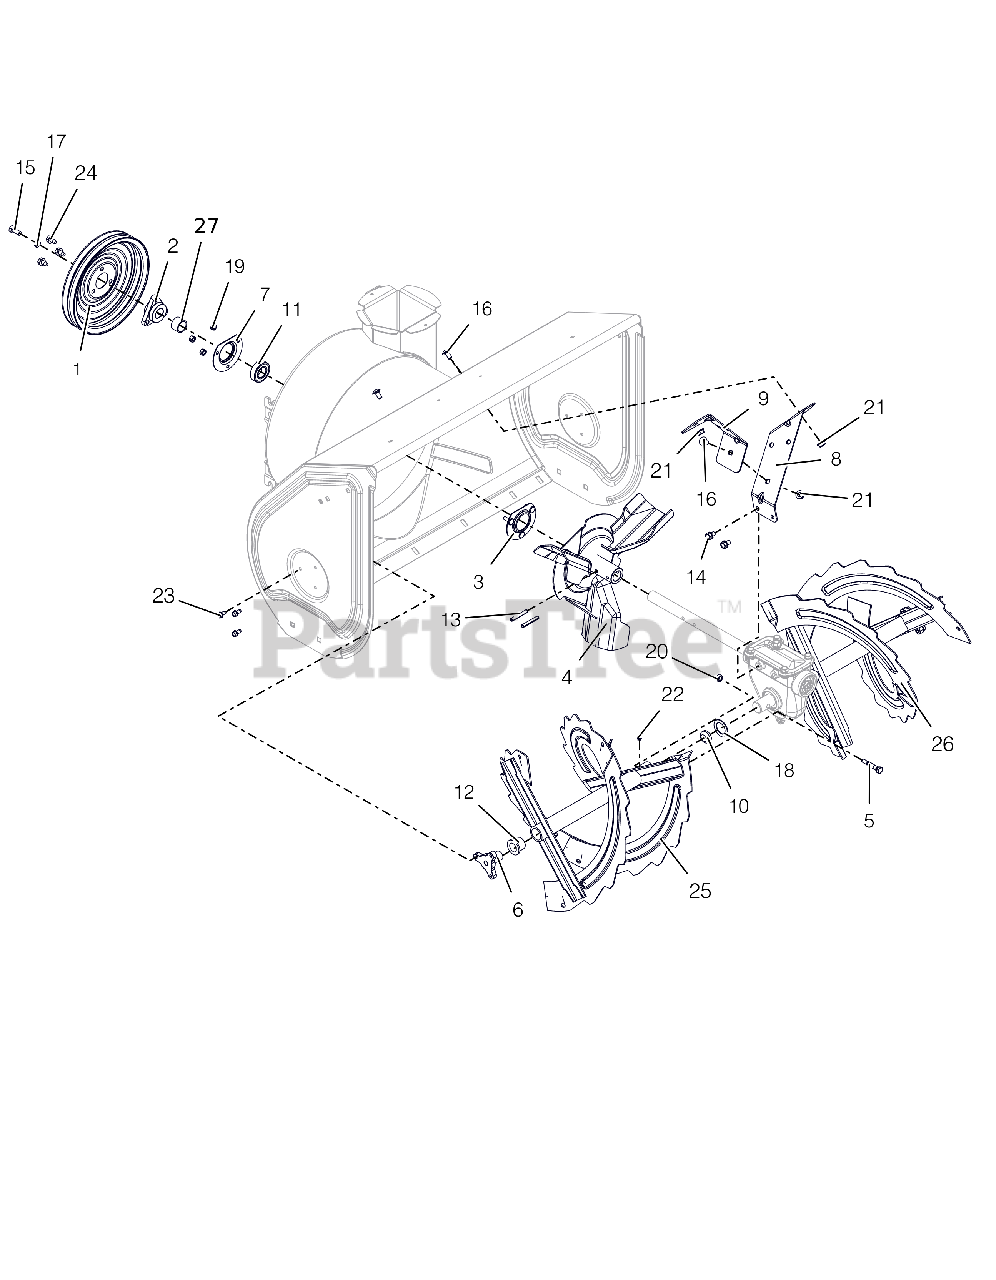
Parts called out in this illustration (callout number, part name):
1	PULLEY, SPIN FORM DUAL GROOVE
2	PULLEY HUB, D-BORE .87 DELUXE
3	BEARING FLANGE
4	IMPELLER, 3 BLADE-14"
5	BOLT, SHEAR - DELUXE
6	SUPPORT, RAKE BUSHING
7	BEARING FLANGE
8	BRACKET, GEARCASE SUPPORT - LH
9	BRACKET, GEARCASE SUPPORT - RH
10	PLUG, RAKE TUBE
11	BRG-BALL .876 X 1.750 X .50
12	BSHG-FLG, NY.778 ID X 1.018 OD
13	PIN-ROLL .250X1.75
14	BOLT, SEMS .31-18X.50 GR5 YWZC
15	BLT-HEX .31-24X.75 YWZC GR5
16	BLT-RDHDSQSHNK.31-18X.62 YZ-LK
17	WSHR-LK .312X.097 HVY YWZC
18	WSHR-FL-STL 1.010X1.505X.062YZ
19	@NUT-LK-CTR .25-20 YWZC
20	@NUT-LK-CTR .31-18 YWZC
21	@NUT-LK-TOP-FLG .31-18 YWZC
22	ZERK,FITTING .25X.125 DRIVE IN
23	SCR-TAP .25-20X.50 HWH TR YWZ
24	@SCR-TAP .31-18X.50 HWH TR YWZ
25	RAKE, RH W/ZERK - 30"
26	RAKE, LH W/ZERK - 30"
27	BSHG,SPCR .895X1.065X.693
